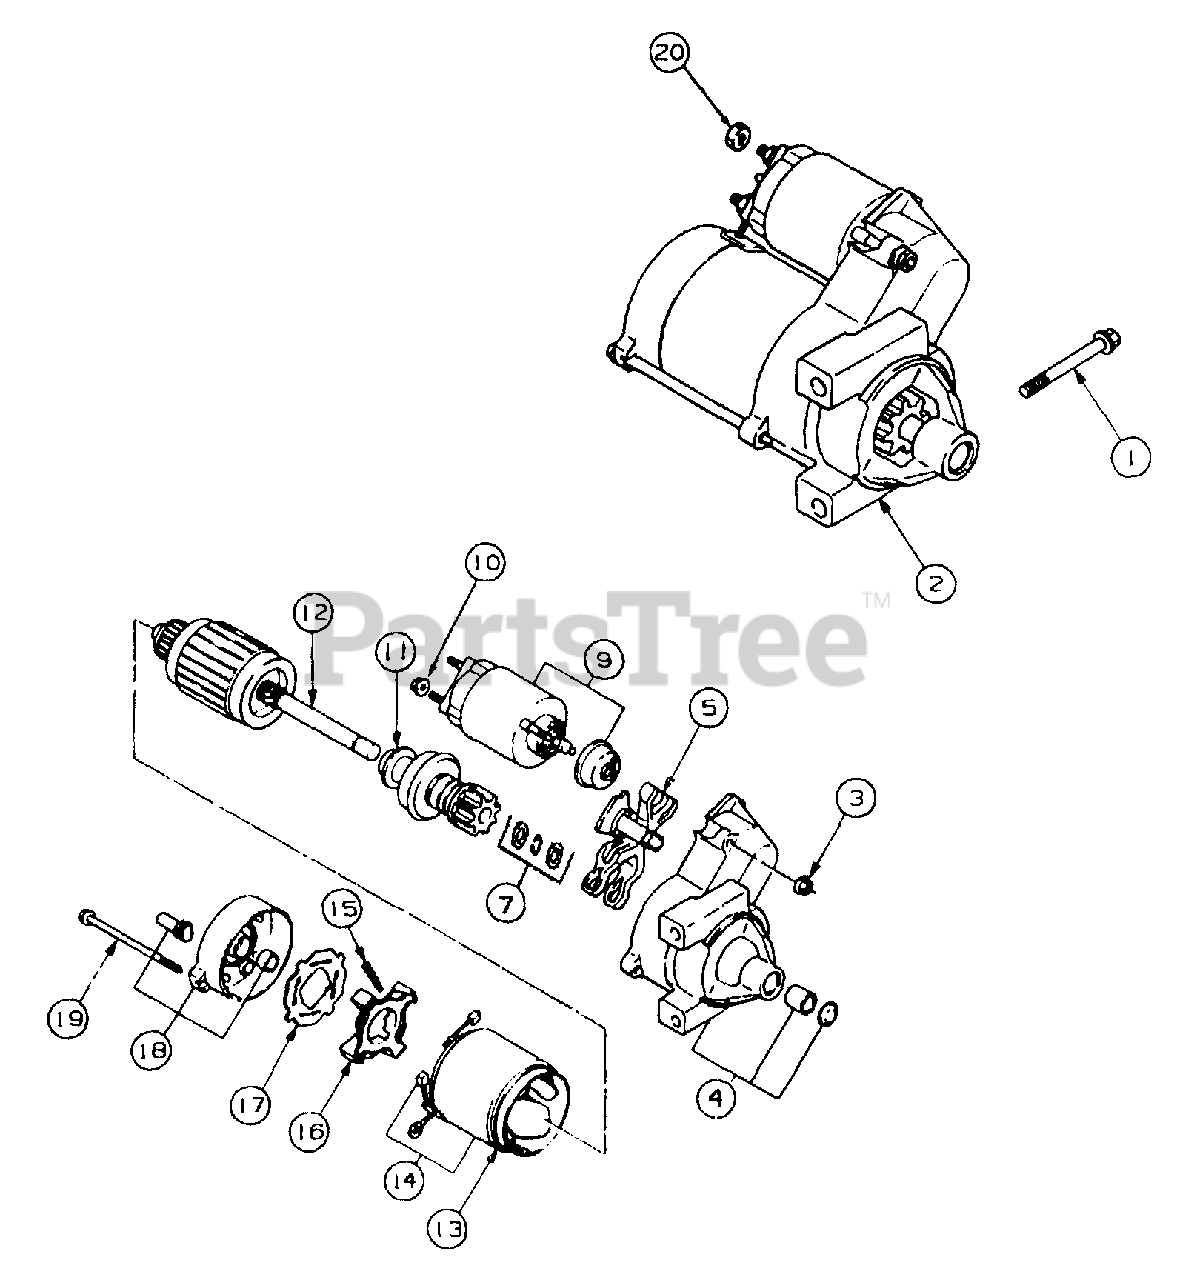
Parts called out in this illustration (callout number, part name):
1	Screw, Bendix Starter, M8 x 1.25 x 80.6
2	Starter, Solenoid Shift Assy
3	Nut, Starter
4	Cap, Drive End
5	Lever, Starter Drive
7	Kit, Starter Repair
10	Nut, Starter
11	Drive, Pinion
12	Armature, Starter
14	Kit, Brush
15	Spring, Brush
16	Holder, Brush
18	Cap, Commutator End
20	Nut, Hex Flange, M8 x 1.25
